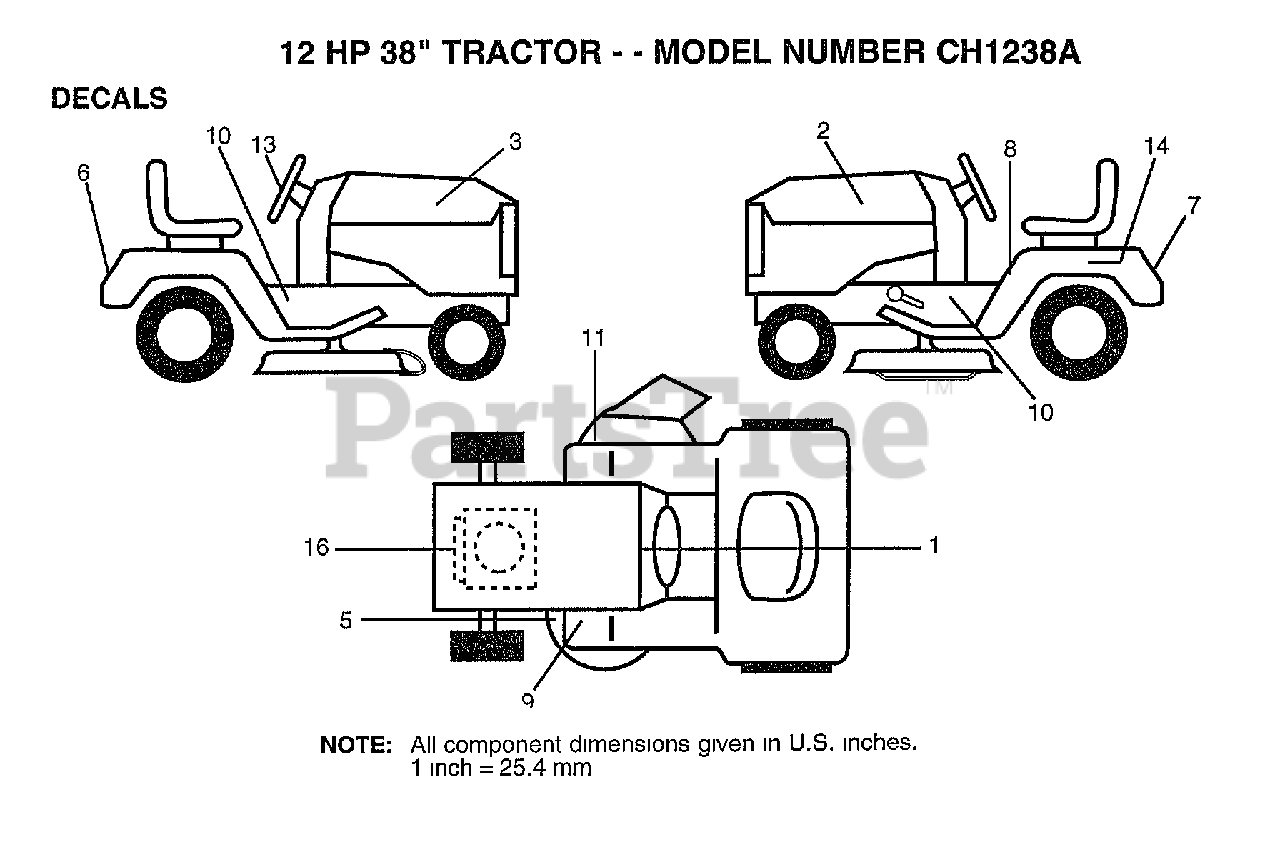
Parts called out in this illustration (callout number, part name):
1	DECAL.DASH.INST.
2	DECAL.HOOD.LH
3	DECAL.HOOD.RH
5	DECAL
6	DECAL.FENDER
8	DECAL
11	"DECAL, WARNING"
13	DECAL.INSRT.STRG
14	DECAL
16	DECAL.ENG.271967
